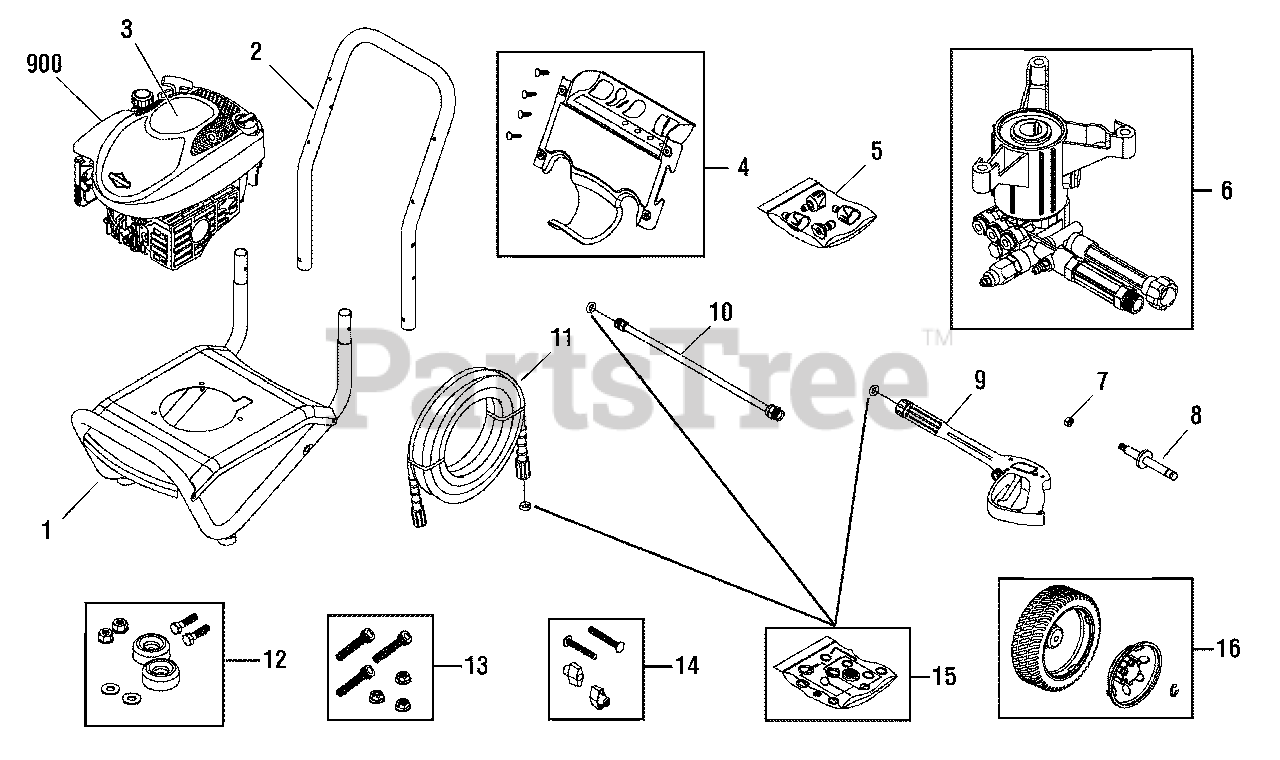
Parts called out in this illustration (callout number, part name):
5	KIT, QC Nozzles
6	PUMP
7	NUT
8	AXLE
9	GUN
10	EXTENSION, QC
12	MOUNT, Vibration
13	KIT, Hardware, Pump Mounting
14	KIT, Hardware, Handle
15	KIT, O-Rings
16	KIT, Wheel
900	* ENGINE
